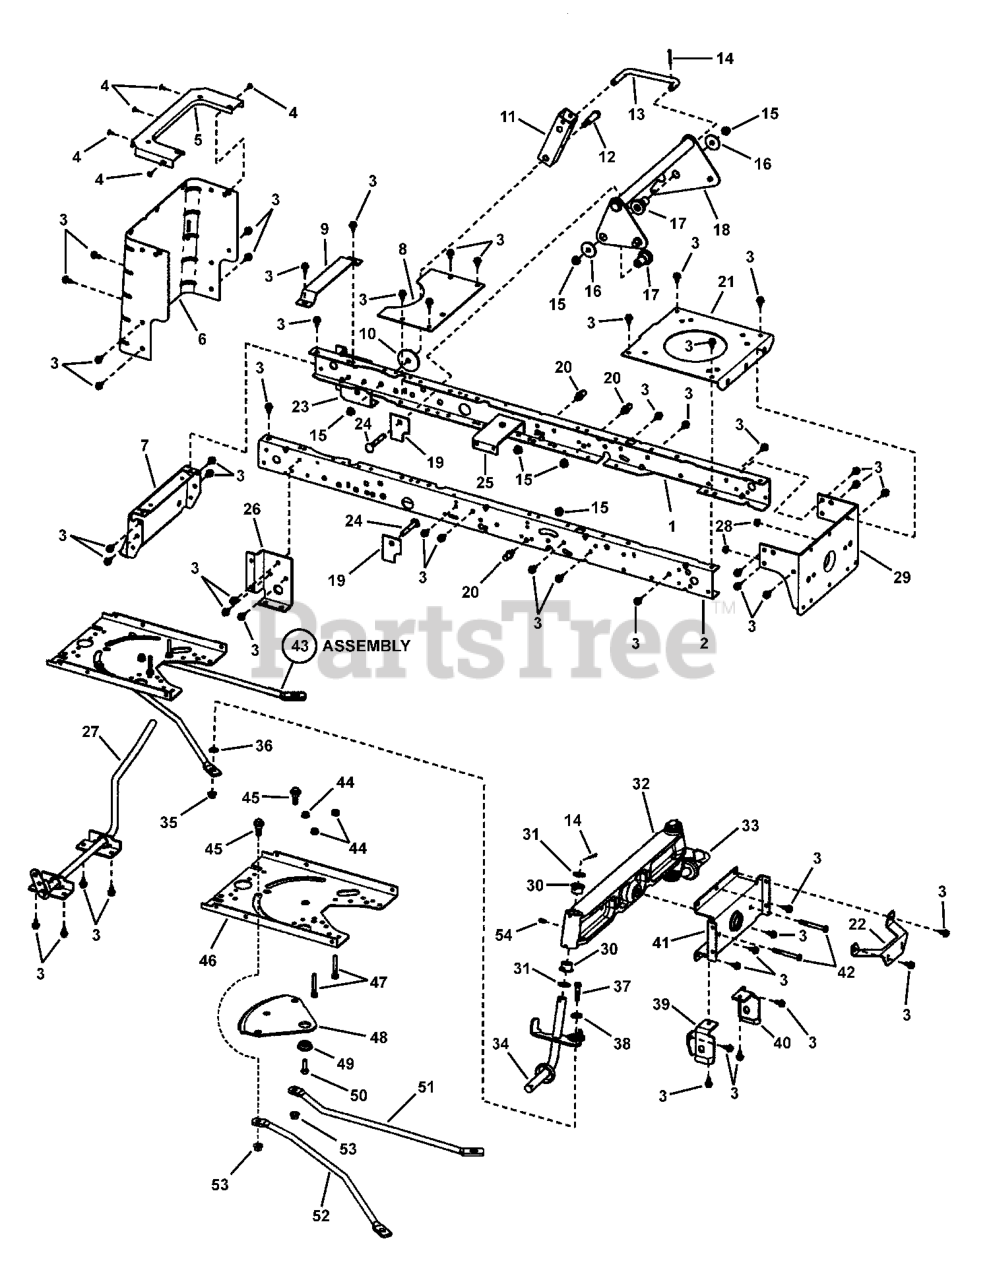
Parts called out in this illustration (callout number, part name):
1	RAIL - FRAME LH
2	RAIL FRAME RH
3	CAPSCREW 5/16-18
4	SCREW, 10-24X.50 SELF-TAP SEMS
5	TOP - REAR PLATE
6	PLATE REAR
7	PLATE - HITCH
8	PLATE, IDLER PULLEY HYDRO GEAR
9	BRKT - BATTERY SUPPORT
10	HER PLAIN .406 X 2.25
11	BRACKET - PIVOT
12	SHOULDER BOLT, 1.563L X 0.75D X 9/16 X 3/8-16
13	LINK - LIFT HANDLE
14	PIN,COTTER 1/8 X 1.25 YZ
15	HFLN, 3/8-16 YZ
16	HER 1-1/2 OD
17	SPACER - LIFTER PIVOT
18	LIFTER ASSY (WELDMENT)
19	PLATE STIFFENING
20	PIN - THREADED SHOULDER (3/8-16 thread)
21	PLATE - ENGINE
22	BRACKET, MUFFLER MOUNTING
23	BRACKET - TRANSAXLE L.H.
24	RHSSNB,3/8CX2-1/2
25	ASSY, IDLER BRKT (SECONDARY)
26	BRACKET - TRANSAXLE R.H.
27	ASSEMBLY - BRAKE LEVER (WELDMENT)
28	HFLN, 5/16-24 BZ
29	BRACKET - HANGER REAR
30	BEARING SPINDLE
31	HER,.77X1.13X.06
32	GT AXLE - CAST IRON
33	WELDMENT - SPINDLE LH
34	WELDMENT - SPINDLE RH
35	NUT, HEX FLANGE, 3/8-16 NC
36	FW, .41 X.82 X 16GA
37	BOLT, HEX, 3/8-16 UNC X 1.50 BRIGHT ZINC
38	HER, FLAT, 25/64" ID X 1" OD X 14 GA.
39	HANGER DECK RH
40	HANGER DECK LH
41	HANGER - AXLE
42	HHB, 5/16-24 X 2.75 BOLT
43	SECTOR GEAR ASSY (GEAR DRIVE - LT) NOT SERVICEABLE
44	HFLN, 5/16-18 BZ
45	BOLT, SHOULDER 3/8-16
46	PLATE, STEERING MOUNT
47	SCREW - GUIDE
48	GEAR - SECTOR
49	BEARING - SECTOR GEAR
50	HHCS, 5/16-18 X 1 YZ
51	DRAG - LINK LH
52	DRAG - LINK RH
53	HFLN, 3/8-16 YZ
54	FITTING - LUBRICATION
